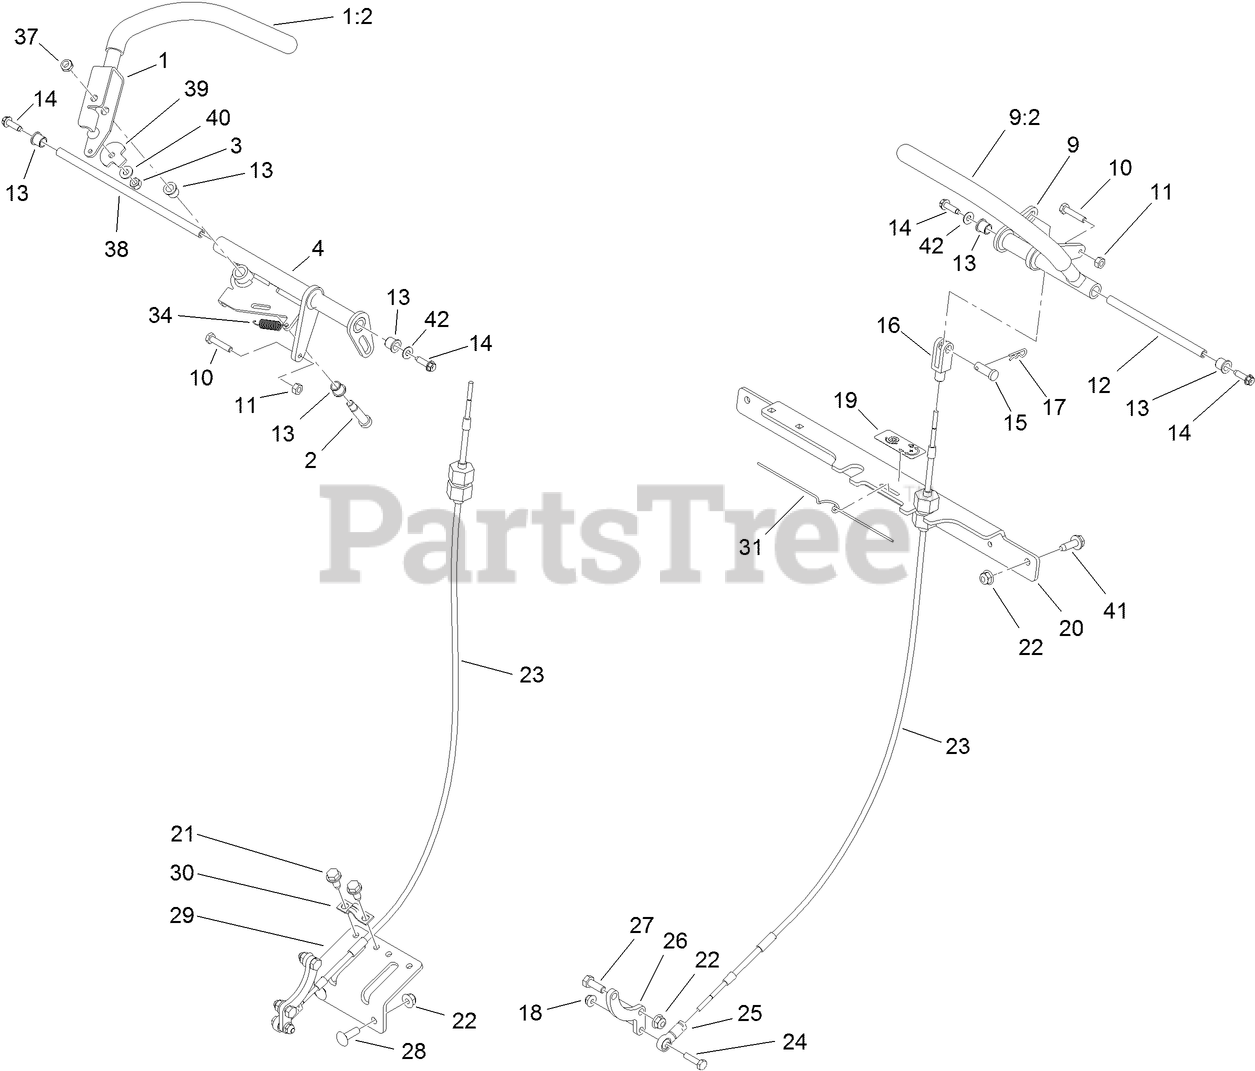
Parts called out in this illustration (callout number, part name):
1	LEVER-MOTION, RH
2	SCREW-HSH
3	NUT-LOCK, NI
4	MOTION CONTROL ASM-RH
9	LH MOTION CONTROL ASM
10	SCREW-HH
11	NUT-HEX
12	SHAFT-PIVOT, MOTION CONTROL
13	BEARING
14	SCREW-HH, TORX
15	PIN-CLEVIS
16	YOKE-FEMALE
17	PIN-COTTER
18	NUT-HF
19	DECAL-TRACKING, HYDRO
20	BRACKET-CROSS
21	SCREW-HWHTF
22	NUT-HF, NI
23	CABLE ASM
24	SCREW-HH
25	ROD END-BALL JOINT
26	ARM-CONTROL, PUMP
27	SCREW-HH
28	BOLT-CARR
29	BRACKET-CLAMP, CABLE
30	CLAMP-CABLE
31	CLIP-SPRING
34	SPRING-EXTENSION
37	NUT-LOCK, NI
38	SHAFT-PIVOT
39	CAM-LEVER
40	WASHER-FLAT
41	SCREW-HHF
42	WASHER-FLAT
